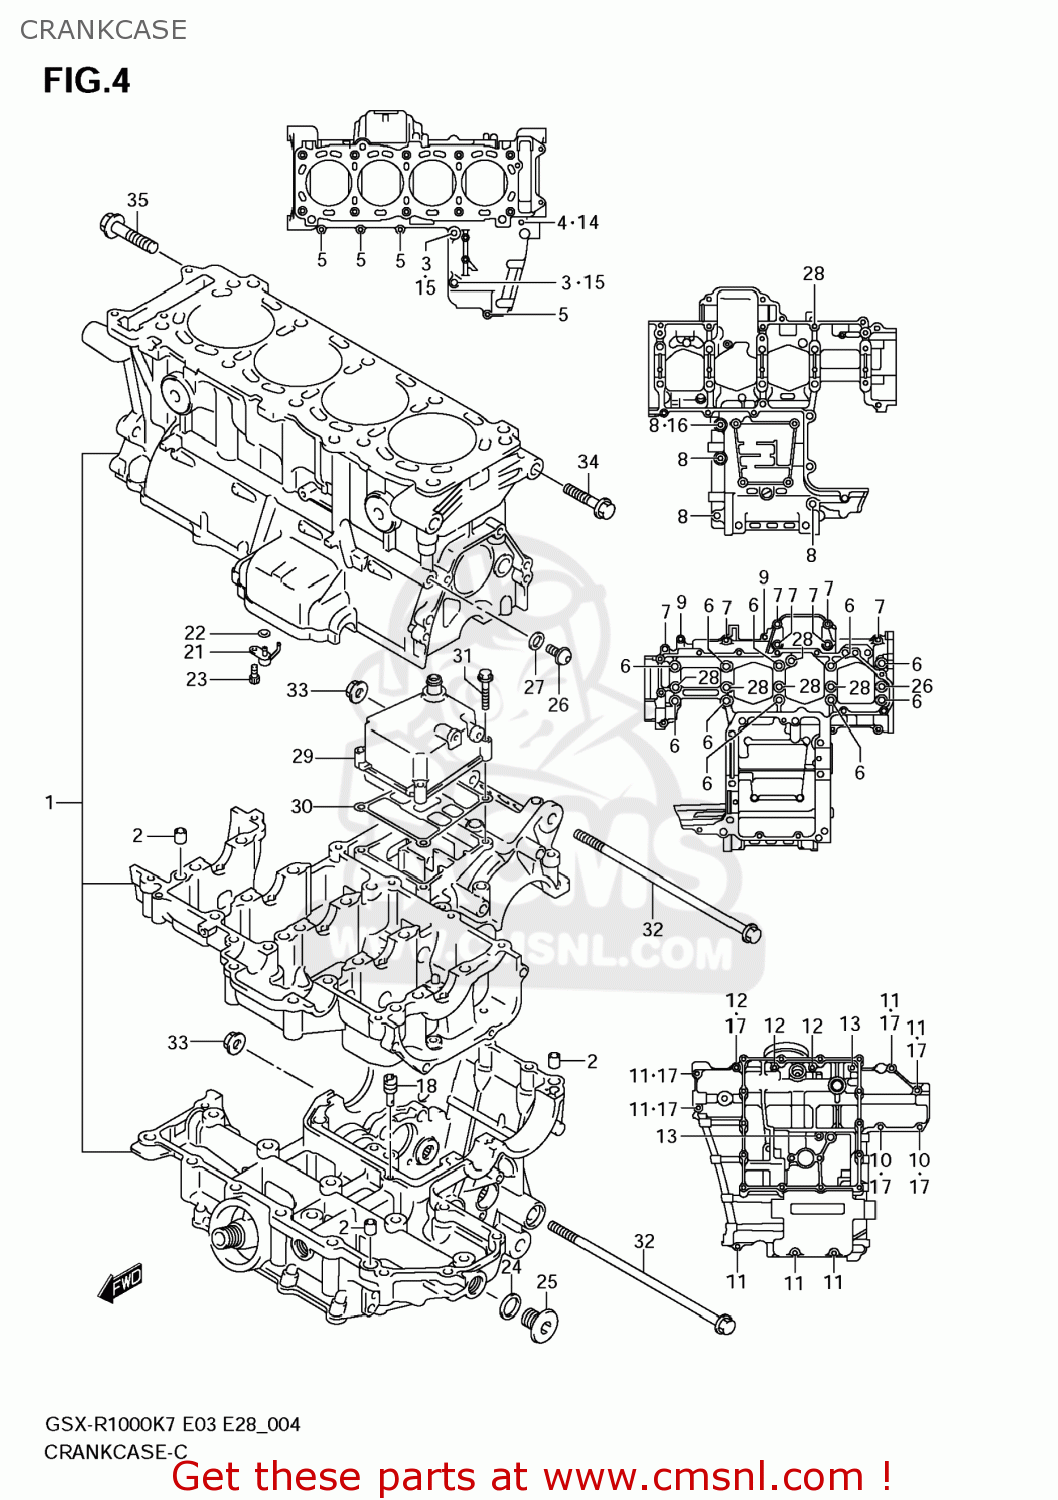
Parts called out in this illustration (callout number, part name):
1	CRANKCASE SET
2	PIN,CRANKCASE
3	BOLT(8X120)
4	BOLT
5	BOLT
6	BOLT(9X95)
7	BOLT
8	BOLT
9	BOLT
10	BOLT
11	BOLT
12	BOLT
13	BOLT
14	GASKET(5.8X13X1.2) (NAS)
15	GASKET(8.2X14X1) (NAS)
16	GASKET(8.2X14X1) (NAS)
17	GASKET(5.8X13X1.2) (NAS)
18	JET(140)
19	BEARING,CRANK THRUST(GREEN)
20	BEARING,CRANK THRUST(RED)
21	JET,PISTON COOLING
22	O RING(D:1.2,ID:4)
23	BOLT(6X12)
24	GASKET(16X22X2) (NAS)
25	PLUG
26	PLUG(10X10)
27	GASKET(10X14X3.6) (NAS)
28	O RING(D:1.9,ID:7.8)
29	COVER,BREATHER
30	GASKET,BREATHER COVER (NAS)
31	BOLT
32	BOLT 10X215
33	NUT
34	BOLT(10X45)
35	BOLT(10X55)
